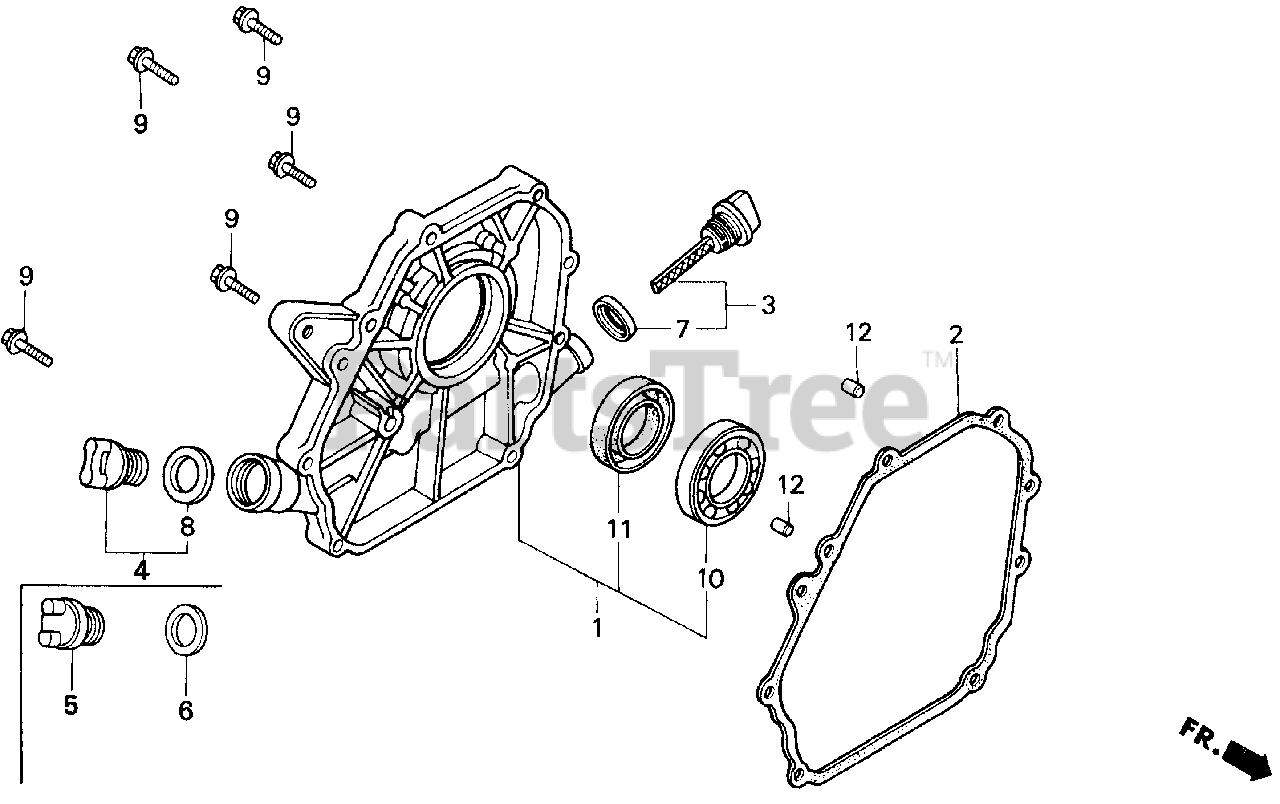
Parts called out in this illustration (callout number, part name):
1	COVER ASSY., CRANKCASE
2	GASKET, CASE COVER
3	CAP ASSY., OIL FILLER (GRAY)
4	CAP ASSY., OIL FILLER
5	CAP, OIL FILLER
6	GASKET, OIL FILLER CAP
7	GASKET, OIL FILLER CAP
8	GASKET, OIL FILLER CAP
9	BOLT, FLANGE (6X28) (CT200)
10	BEARING, RADIAL BALL
11	OIL SEAL (22X41X6)
12	PIN, DOWEL (8X14)
